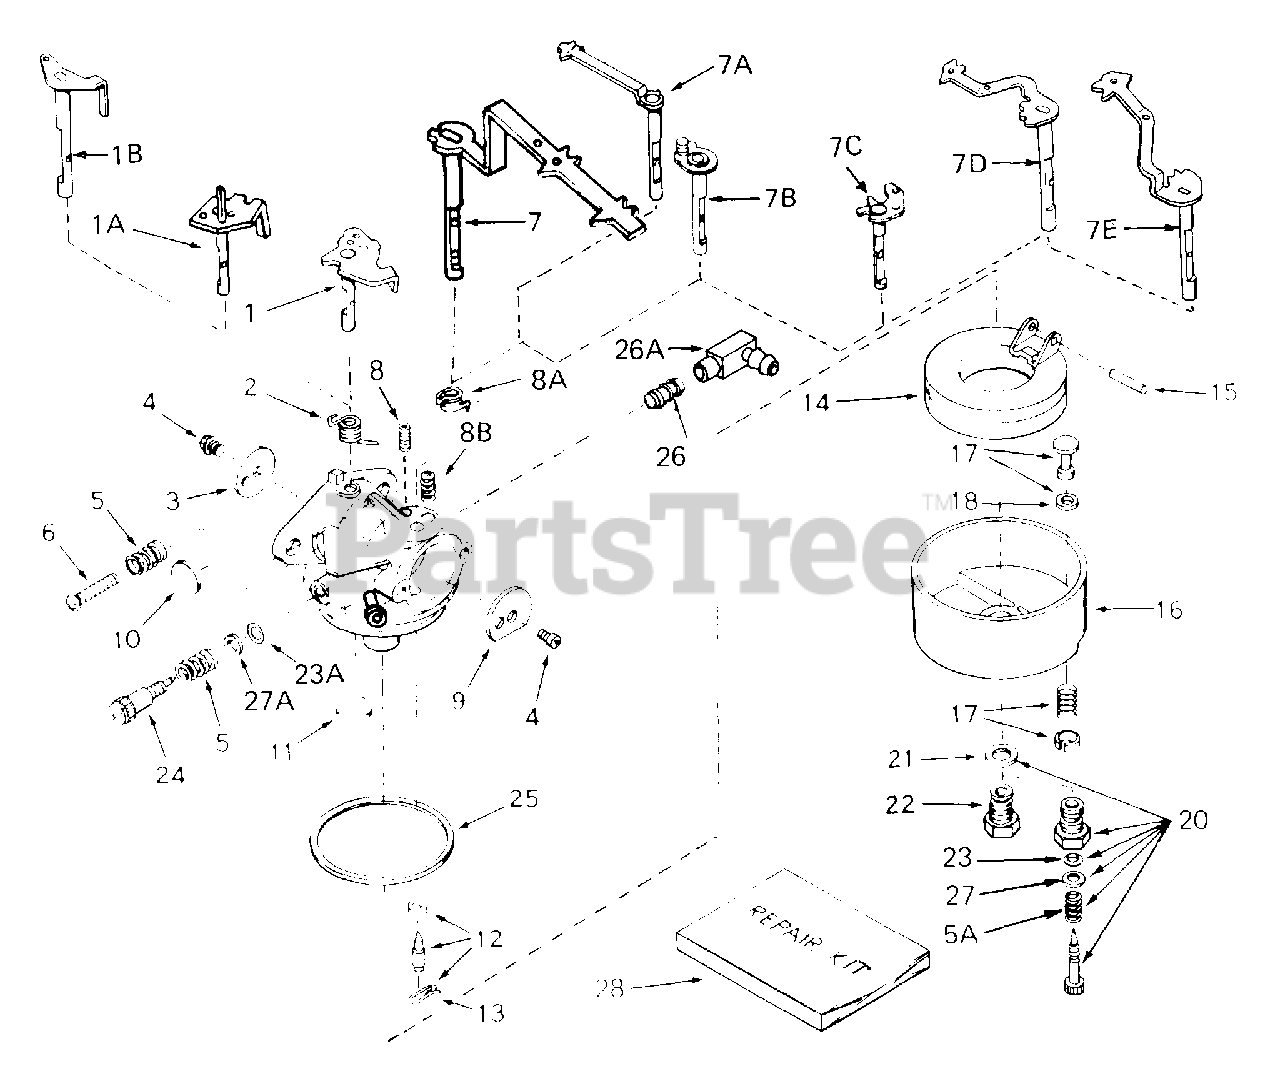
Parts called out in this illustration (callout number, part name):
1	"Shaft & Lever Assy., Throttle
2	Spring, Throttle return
3	Shutter, Throttle
4	Screw, 4-40 x 3/16
5	Spring, Regulating screw
5A	Spring, Main adjustment screw
6	Screw, Idle regulating
7A	Shaft & Lever Assy., Choke
8B	Spring, Choke positioning
9	Shutter, Choke
10	Plug, Welch
11	Plug, Welch
12	Inlet Needle, Seat & Clip
13	Clip, Inlet needle
14	Float, Carburetor
15	Shaft, Float
16	Bowl, Float
17	Plunger Assy., Drain
18	Gasket, Drain plunger
20	Adjustment Screw Assy., Main
21	Gasket, Bowl-to-body
23	"O" Ring, Adjustment screw
23A	"O" Ring, Adjustment screw
24	Screw, Idle adjustment
25	Gasket, Bowl-to-body
26	Fitting, Fuel inlet
28	Repair Kit
